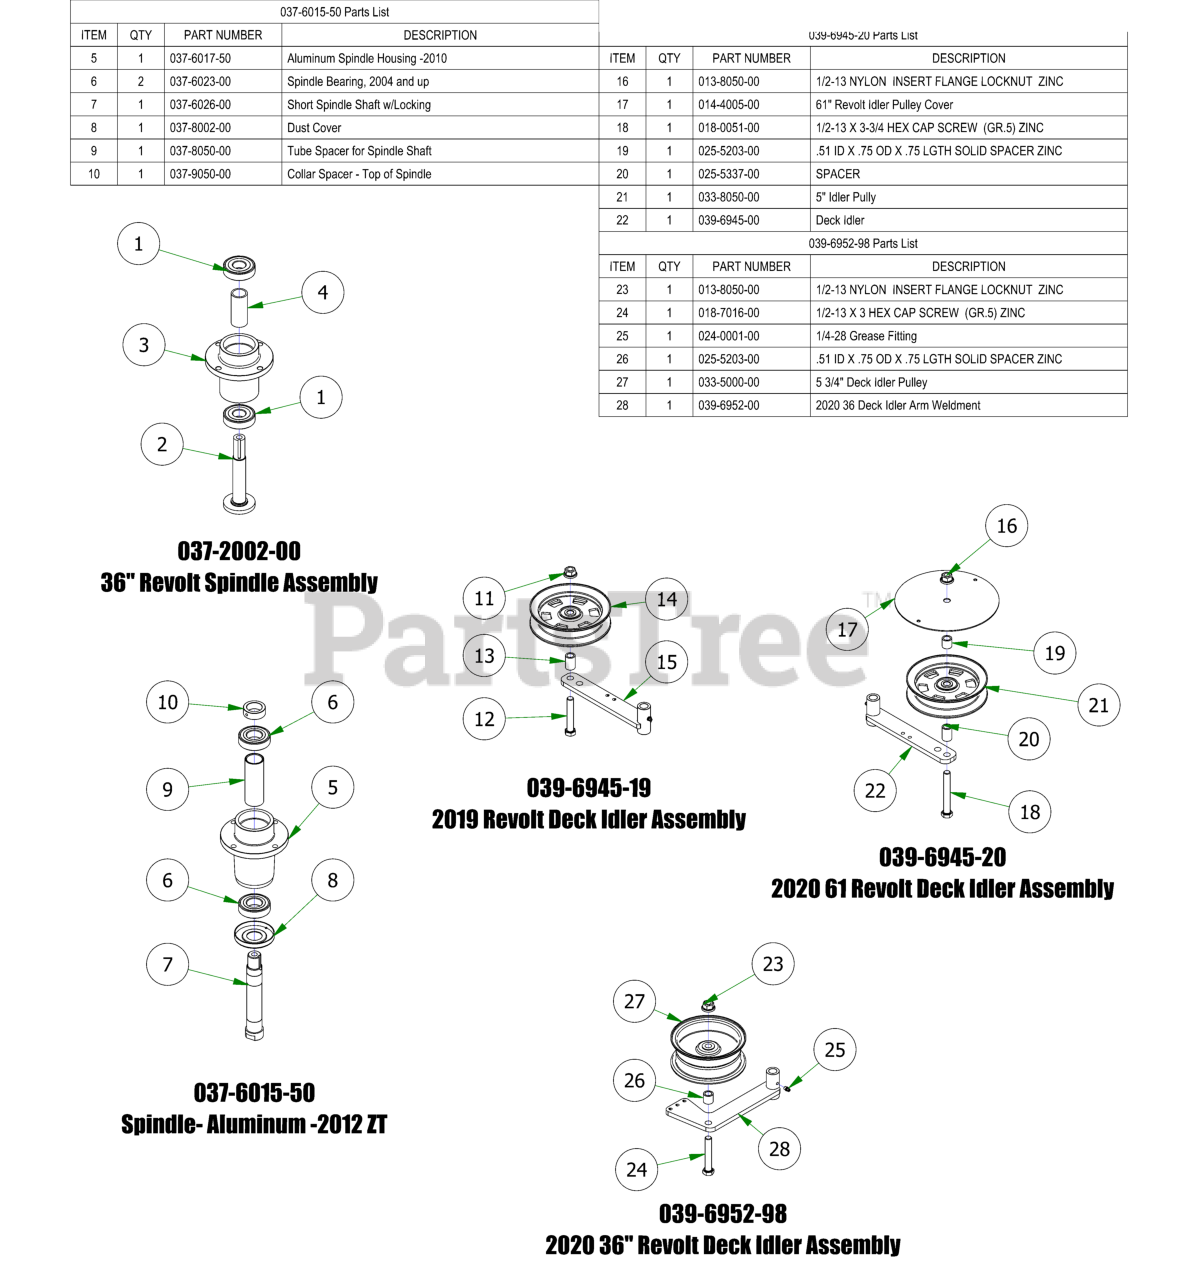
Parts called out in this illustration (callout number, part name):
1	Spindle Bearing
2	36'' Revolt Spindle
3	Spindle Housing
4	Spindle Spacer-Component
5	Aluminum Spindle Housing -2010
6	Spindle Bearing, 2004 and up
7	Short Spindle Shaft w/Locking
8	Dust Cover
9	Tube Spacer for Spindle Shaft
10	Collar Spacer - Top of Spindle
11	1/2-13 NYLON INSERT FLANGE LOCKNUT ZINC
12	1/2-13 X 3 HEX CAP SCREW (GR.5) ZINC
14	5" Idler Pully
15	Deck Idler
16	1/2-13 NYLON INSERT FLANGE LOCKNUT ZINC
17	61" Revolt Idler Pulley Cover
18	1/2-13 X 3-3/4 HEX CAP SCREW (GR.5) ZINC
19	.51 ID X .75 OD X .75 LGTH SOLID SPACER ZINC
21	5" Idler Pully
22	Deck Idler
23	1/2-13 NYLON INSERT FLANGE LOCKNUT ZINC
24	1/2-13 X 3 HEX CAP SCREW (GR.5) ZINC
25	1/4-28 Grease Fitting
26	.51 ID X .75 OD X .75 LGTH SOLID SPACER ZINC
27	5 3/4" Deck Idler Pulley
28	2020 36 Deck Idler Arm Weldment
